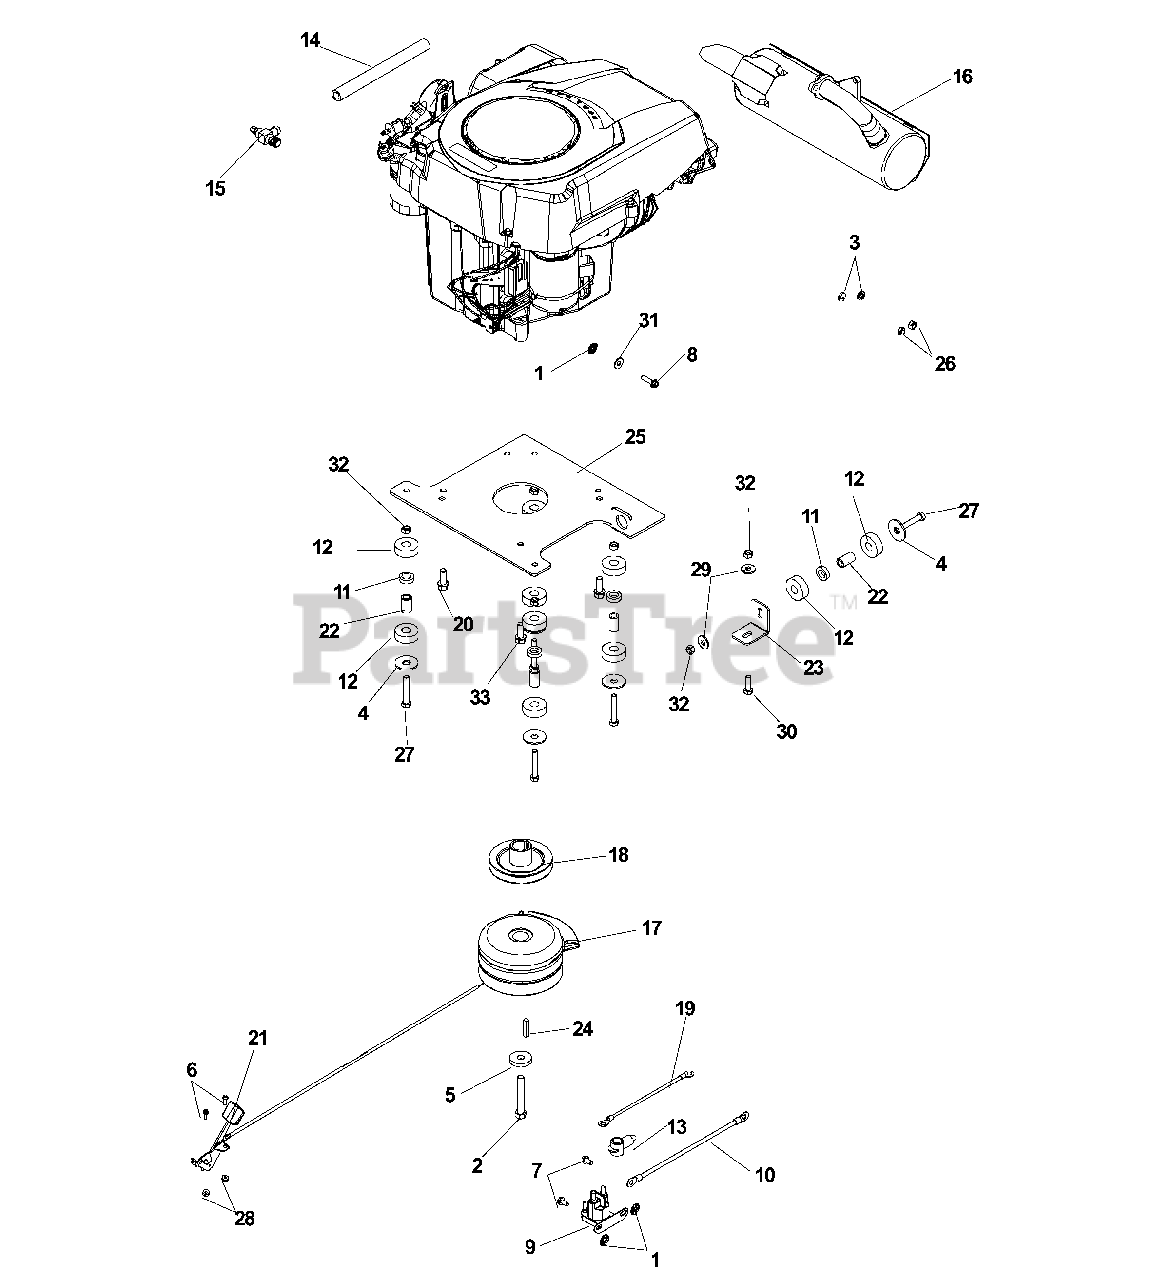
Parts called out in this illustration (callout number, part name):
1	WASHER 1/4 EXTLW STAR ZD
2	HCS 7/16-20 X 2-3/4
3	5/16HELICAL L-WASHER
4	7/16 HD FLAT WASHER
5	WASHER .43X1.38X.25
6	#10-24X5/8PHIL PANHD
7	1/4-20 X 1/2 HWH FORM SCR H
8	1/4-20X 1 HWH TAP SC
9	SOLENOID
10	BATTERY GROUND CABLE
11	ISO-MOUNT INSERT
12	ISO-MOUNT BUSHING
13	TERMINAL COVER-SM
14	OIL DRAIN HOSE
15	OIL DRAIN
16	MUFFLER
17	ELEC. CLUTCH
18	ENGINE PULLEY
19	SOLENOID TO STARTER CABL
20	SCREW, TAP 3/8-16X1 HWH
21	THROTTLE CABLE
22	ISO MT. BUSHING
23	ISO MT. BRKT.
24	KEY 1/4`SQ X 1-1/4`
25	ISO-MT SPDZTR
26	NUT M8 X 1.25 STD HEX
27	HCS 5/16-18X2
28	NUT 10-24 NYLOC
29	FLAT WASHER 5/16 SAE
30	HCS 5/16C X 1
31	WASHER 1/4 FLAT
32	NUT 5/16 NYLOC
33	BOLT 5/16C X 2 1/2
